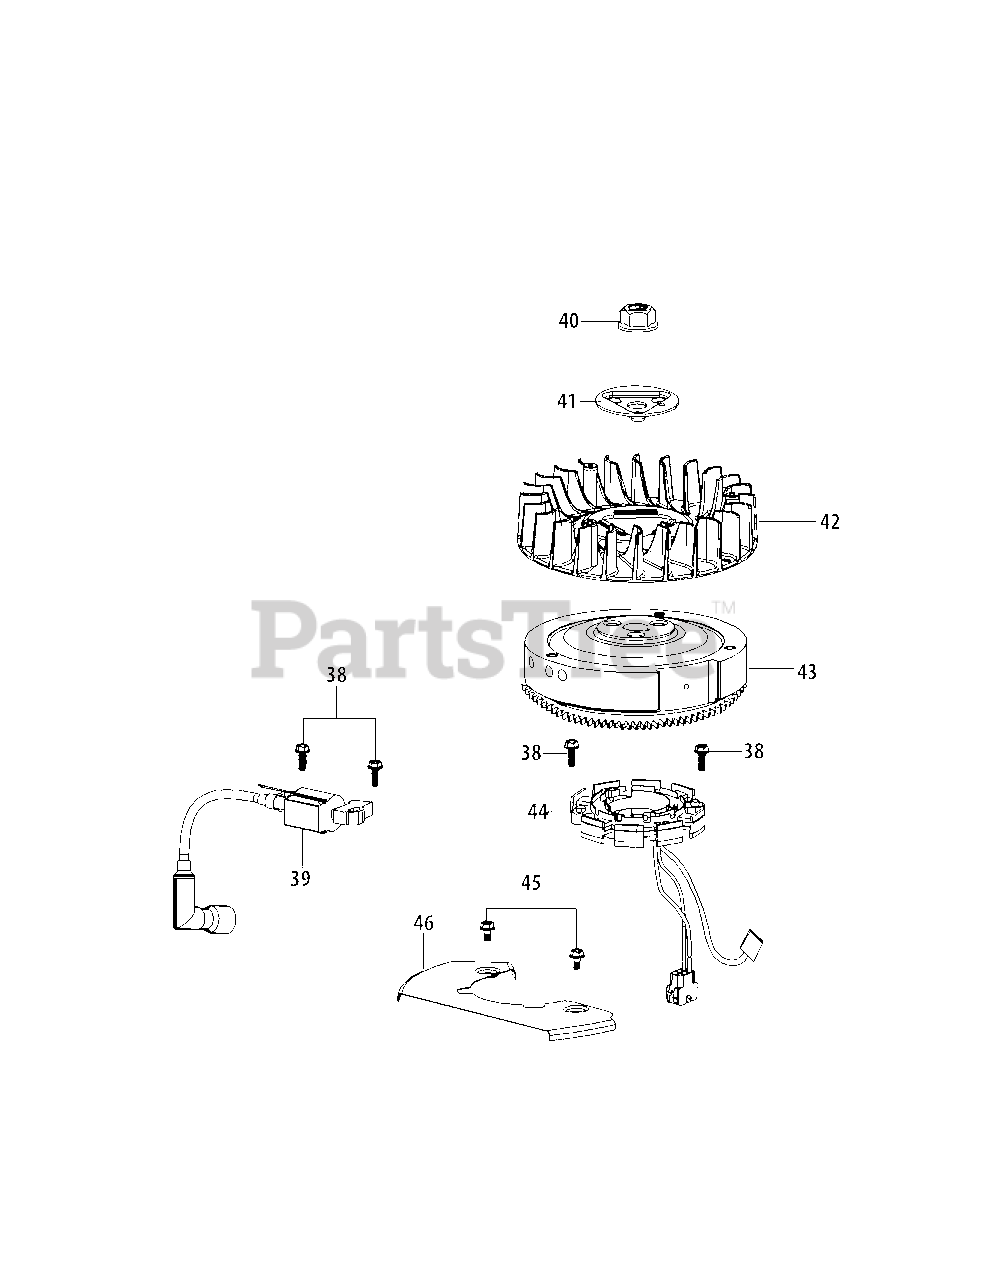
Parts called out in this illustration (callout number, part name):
38	Bolt M6×28
39	Ignition Coil Assembly
40	Flywheel Nut M16×1.5
42	Cooling Fan
43	Flywheel
44	Coil Assy., Charge
45	Bolt M6×10
